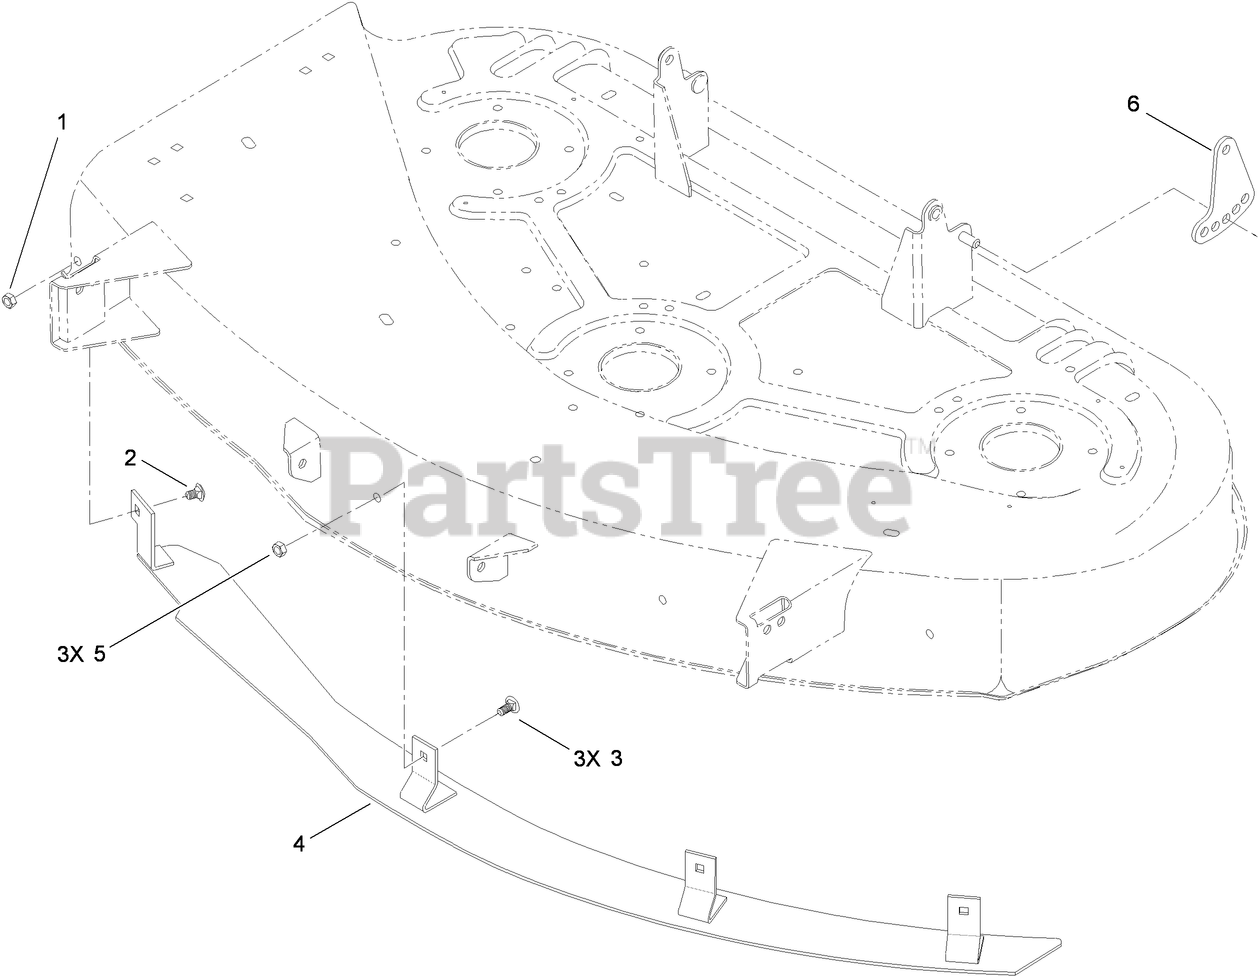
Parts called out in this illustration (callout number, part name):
1	NUT-LOCK, NI
2	BOLT-CARR
3	SCREW-CARR
5	NUT-LOCK, NI
6	LINK-ADJUSTING, HOC
